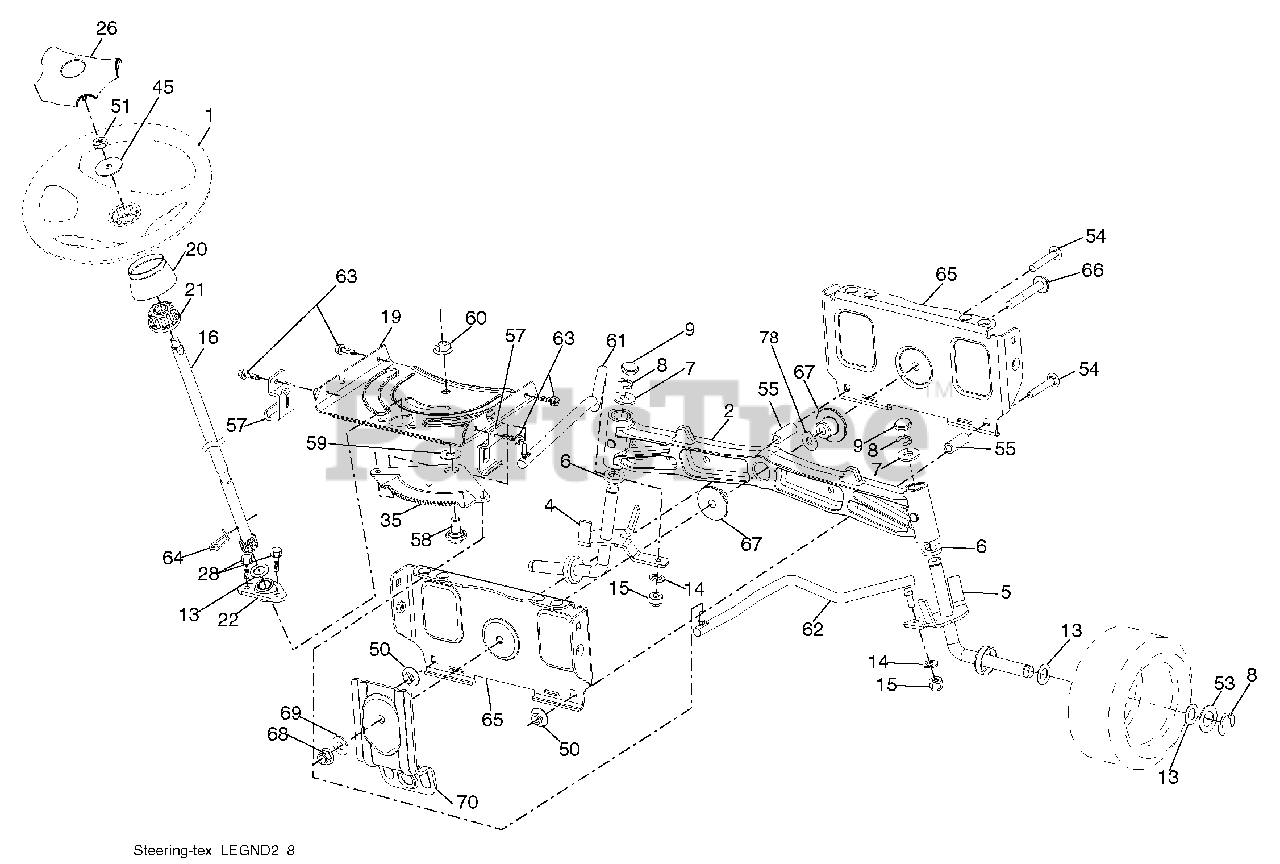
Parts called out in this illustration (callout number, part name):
1	Wheel, Steering
2	Axle Asm., Front
4	Spindle Asm., LH
5	Spindle Asm., RH
6	Bearing, Race Thrust Harden
7	Washer 25/32 x 1-5/8 x 16 Ga.
8	Ring, Clip #T5304-75
9	Cap, Spindle
13	Washer 25/32 x 1-1/4 x 16 Ga.
14	Washer, Lock Hvy Hlcl Spr 3/8
15	Nut, Crown Lock 3/8-24 unf
16	Shaft Steering
19	Plate Steering
20	Boot, Steering
21	Adapter, Wheel Steering
22	Bushing, Strg. Blk
26	Insert, Wheel Steering
28	Screw 3/8-16 x 3/4
35	Gear, Sector Plate
45	Washer 9/16 ID x 2-3/8 x 12 Ga.
50	Nut Lock 3/8-16 unc
51	Nut Hex Jam Toplock 1/2-20 unf
53	Washer Hardened .793 x 1.637 x .060
54	Bolt Hex 3/8-16 unc x 2-1/4
55	Spacer Brace Axle
57	Bracket Upstop
58	Bolt Shoulder Sector Pivot CFM
59	Washer Thrust Sector Steering
60	Nut Flange Lock 5/8-11
61	Draglink, LH
62	Draglink, RH
63	Screw 5/16-18 x 3/4
64	Retainer Clip Spring Steering
65	Brace Axle Front
66	Bolt Hex Fghd 7/16-14 x 3 Serr
67	Bushing PM Front Axle
68	Nut Lock Flange 7/16-14 Gr. 5
69	Washer 1.5 x .505 x .118
70	Bracket Deck Susp. Front
78	Washer Thrust .515 x .750 x .033
